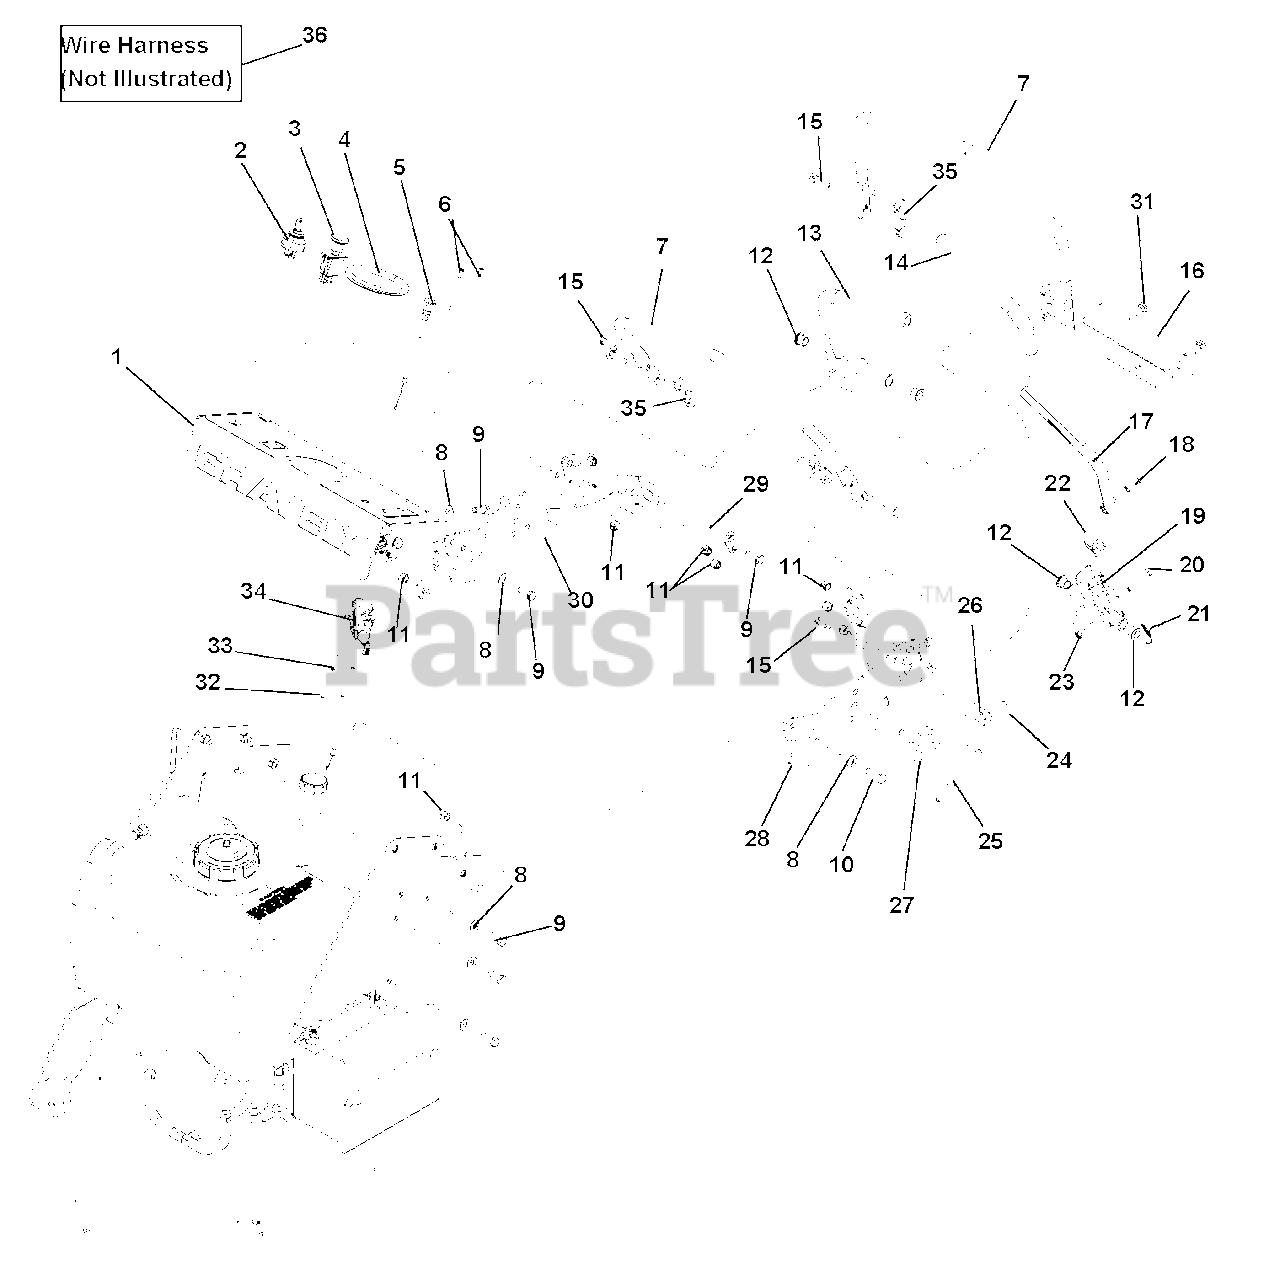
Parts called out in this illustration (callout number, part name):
1	ASSY, CONSOLE W/DECALS
2	SWITCH, KEY - 3 POSITION
3	SWITCH, PTO ENGAGEMENT
4	TRIM, RUBBER EDGE 12"
5	CABLE, CHOKE 48"
6	SCREW, 8-32 X .50 PAN PHL Y
7	SUPPORT, HANDLE
8	WASHER, .406 X .813 X .065 FLAT Y
9	BOLT, 3/8-16 X 1.00 HEX 5
10	BOLT, .38-16 X 1.25 HEX 5 Y
11	LOCKNUT, 3/8-16 NYLOC Y
12	BRG, FLG .500 X .625 X .500 BRNZ
13	WLDT, RH DRIVE LEVER
14	GRIP, CONTROL
15	BOLT, RDHDSQNK .38-16 X 1.25 G5
16	DRIVE ARM BACK PLATE
17	WLDT, LH DRIVE LEVER
18	SPACER, .330 X .500 X .980
19	WLDT, LH HANDLE MOUNT
20	BOLT, .31-18 X 1.75 HEX 5 Y
21	BOLT, .31-18 X 1.75 HEX 5 Y
22	SWITCH, SEAT OVER RIDE (N.O.)
23	LOCKNUT, 5/16-18 NYLOC Y
24	PIN, SPRING
25	LEVER, LOCK Y
26	BASE, LOCK LEVER Y
27	KNOB, 3/8 X 1.25 - 4 PRONG
28	WLDT, LH HANDLE MOUNT 5 DEG
29	WLDT, PIN AND LOCK
30	WLDT, RH CONTROL MOUNT
31	BOLT, RDHDSQNK .38-16 X .75 G5Y
32	NUT, 8-32 STD HEX Y
33	WASHER, #8 MED SPRG LOCK Y
34	CABLE, THROTTLE - 49.5
35	SHIM, 5 DEG SPEED BAR
